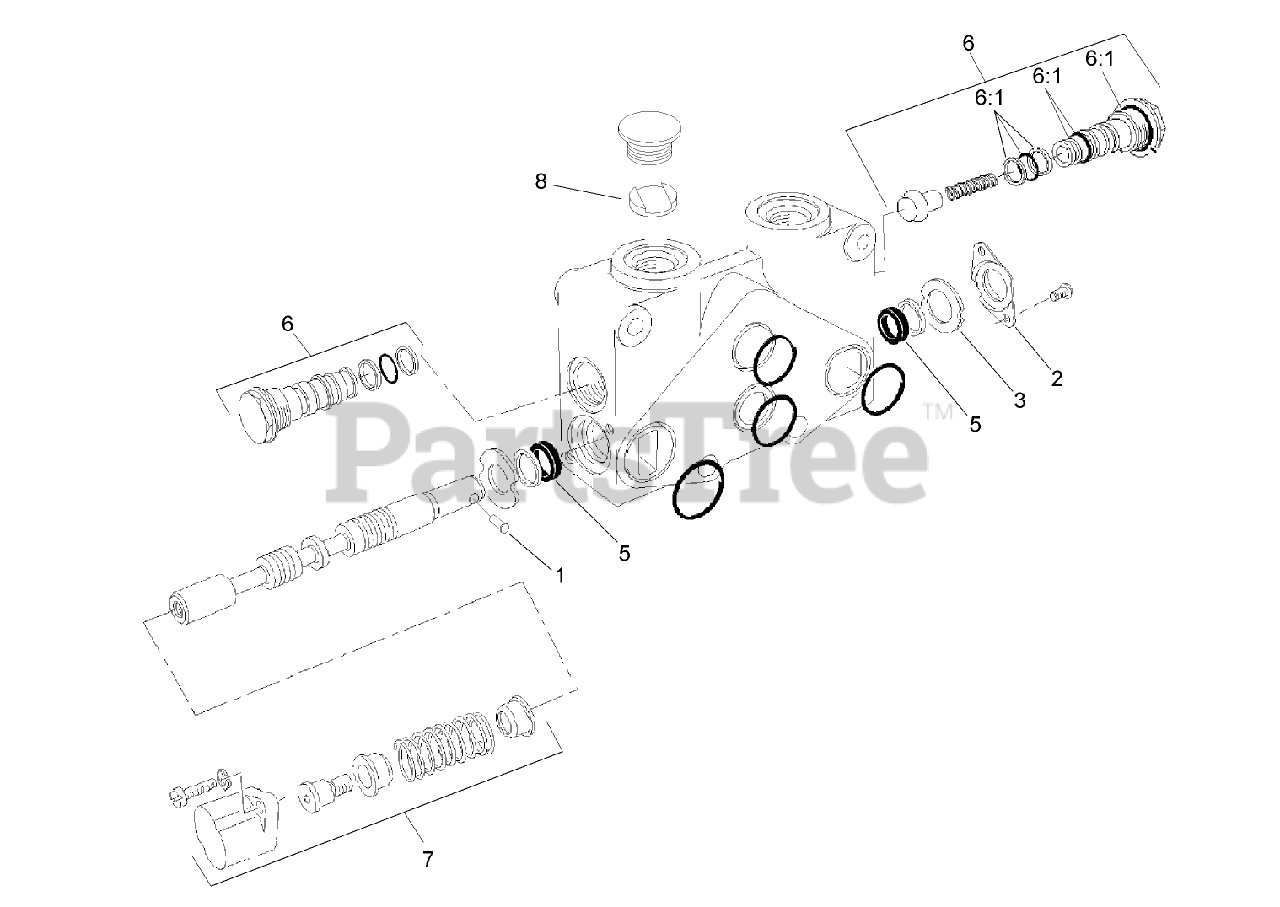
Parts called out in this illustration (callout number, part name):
1	PIN-CLEVIS
2	PLATE-RETAINER, SEAL
3	PLATE-RETAINER, SEAL
5	SPOOL SEAL KIT
6	CARTRIDGE-CHECK
6:1	CARTRIDGE SEAL KIT
7	SPOOL POSITIONER KIT
8	RESTRICTOR (.062IN)
